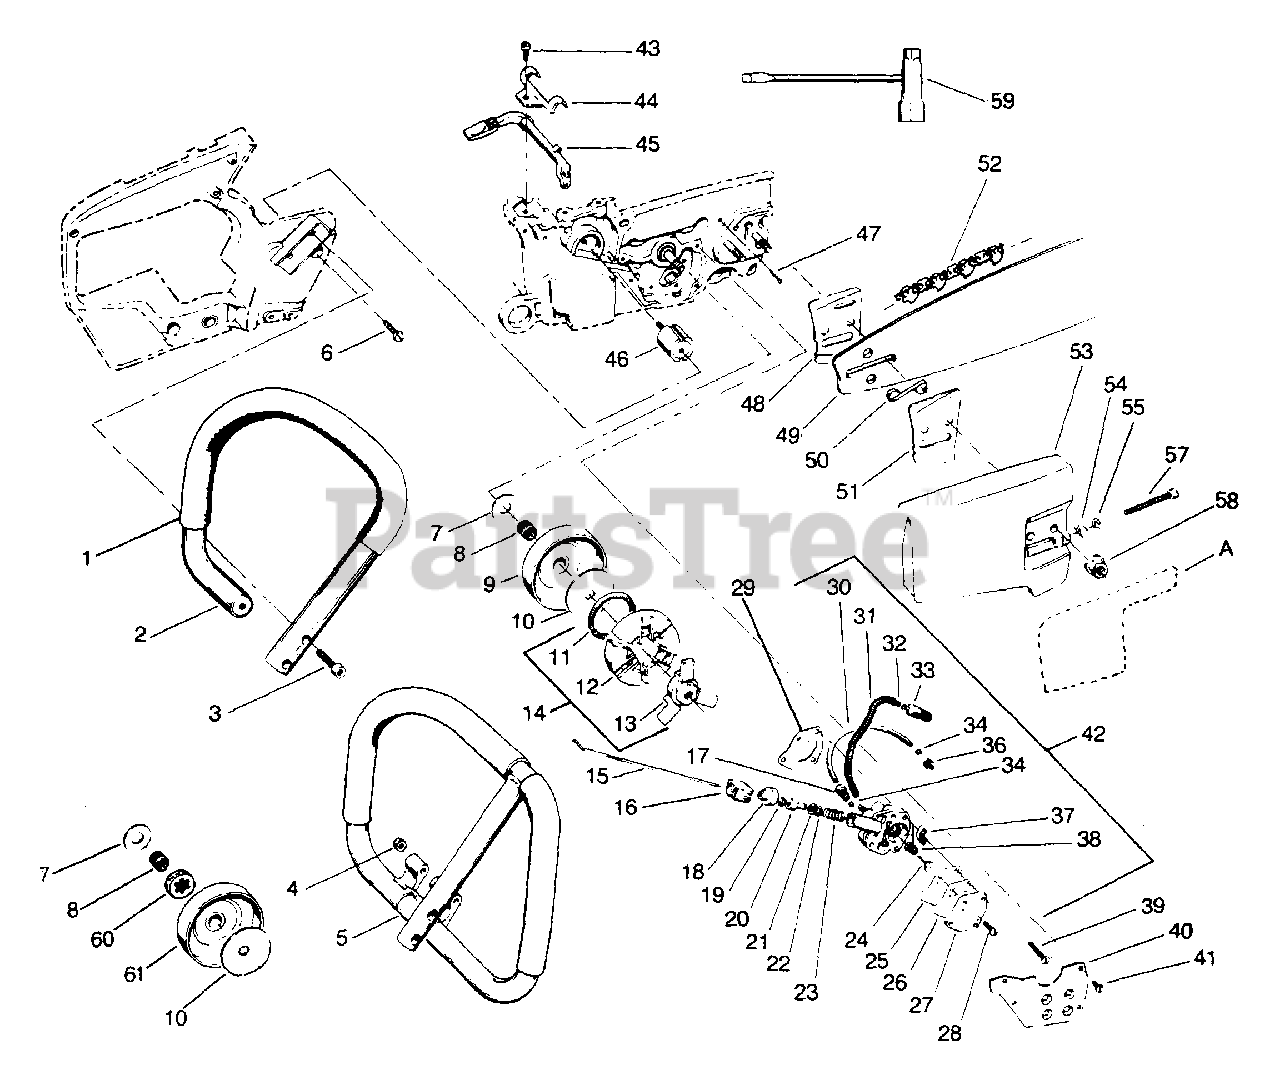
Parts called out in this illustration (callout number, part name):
1	Kit - Grip - Handlebar (Velvet)
2	Handlebar Assembly
2	For new Style Handguard
2	For Old Style Handguard
3	Screw - 1/4-20 x 1 - Socket Hd. - Handlebar to Crankcase
4	Locknut - 1/4-20 - Wraparound Handle
5	Handlebar - Wraparound Handle
6	Screw - 10-24 x 1/2 - Pan. Hd. - Side Isolator
7	Thrust Washer
8	Bearing - Clutch
9	Drum & Sprocket Assembly
10	Plate Clutch
11	Spring - Clutch
12	Shoe - Clutch
13	Spider - Clutch
14	Clutch Ass'y.
15	Rod - Manual Oiler
16	Boot - Oiler Rod
17	Tubing Nut
18	Cap - Oil Pump
19	Retainer Ring
21	"O" Ring - Quad Ring
22	Washer - Oiler
24	Ass'y. - Button & Pintle
25	Diaphragm
26	Gasket - Cover to Body
27	Cover - Pump
28	Screw - 8-16 x 5/8 Pan. Hd. - Oil Pump Cover
29	Gasket - Oiler Ass'y to Crankcase
30	Discharge Line Oil
31	Spring-Oil Line Protector
32	Oil Line
32	Oil Line Pick-up Assembly
33	Weight - Oil Pick-up Line
34	Sleeve - 1/8 Tubing
36	Tubing Nut - Slotted
37	Foam - Oil Pump Vent
38	Spring - Diaphragm
39	Screw - 8-32 x 1 - Pan.Hd. - Pump to Crankcase
40	Cover Plate - Oiler
41	Screw - 8-32 x 5/16 - Pan. Hd. - Cover Plate
42	Kit - Oil Pump Ass'y.
43	Screw - 10-24 x 3/8-Fil. Hd. - Bracket to Crankcase
44	Bracket Lever to Crankcase
45	Lever - Manual Oiler
46	Isolator Side
46	Use on Guide Bar Powerhead
46	Use on Bow Guide Powerhead
47	Kit - Oil Vent Replacement
48	Guide Bar Plate - Inner
49	Guide Bar and Bow Guide
50	"S" Clip
51	Guide Bar Plate - Outer
52	Chain
53	Bar Clamp Ass'y
53	Use on Guide Bar Powerhead
53	Use on Bar Guide Powerhead
54	Pin-Bar Adj.
55	"E" Ring Adj. Screw
57	Screw - 10-24 x 2-5/16" Bar Adj.
58	Flange Nut Mounting - 5/16-18
60	Rim-Floating
61	Ass'y Drum & Sprocket
A	Decal - Bar Clamp
